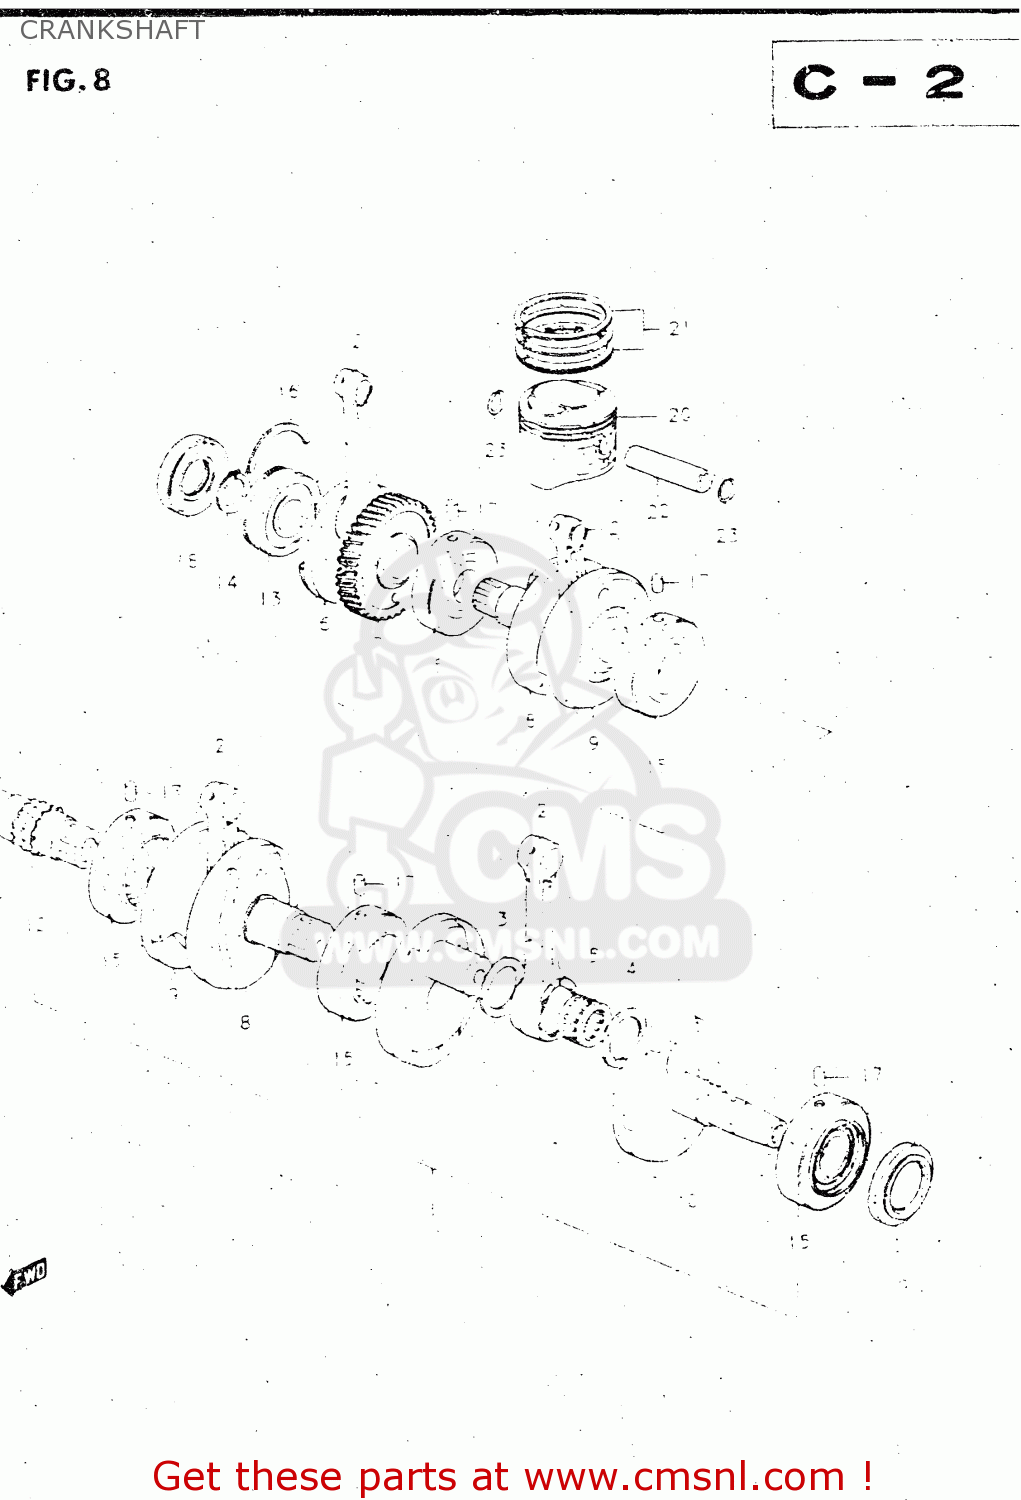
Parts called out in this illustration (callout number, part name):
1	CRANKSHAFT ASSEMBLY
2	ROD,CONNECTING
3	WASHER (28X48X2)
4	WASHER(28X48X1)
5	ROLLER BEARING (28X38X16.8)
6	CRANKSHAFT
7	WEB,CRANK
8	CRANKSHAFT
9	WEB,CRANK,MIDDLE
10	CRANKSHAFT,LEFT
11	WEB,CRANK,LEFT
12	SHAFT,TIMING CHAIN DRIVE
13	BEARING(30X72X19)
14	CIRCLIP,30MM
15	BEARING
16	C RING
17	PIN
18	SEAL,OIL(30X72X11)
19	OIL SEAL
20	PISTON
21	RING SET,PISTON
22	PIN,PISTON 16MM
23	CIRCLIP
